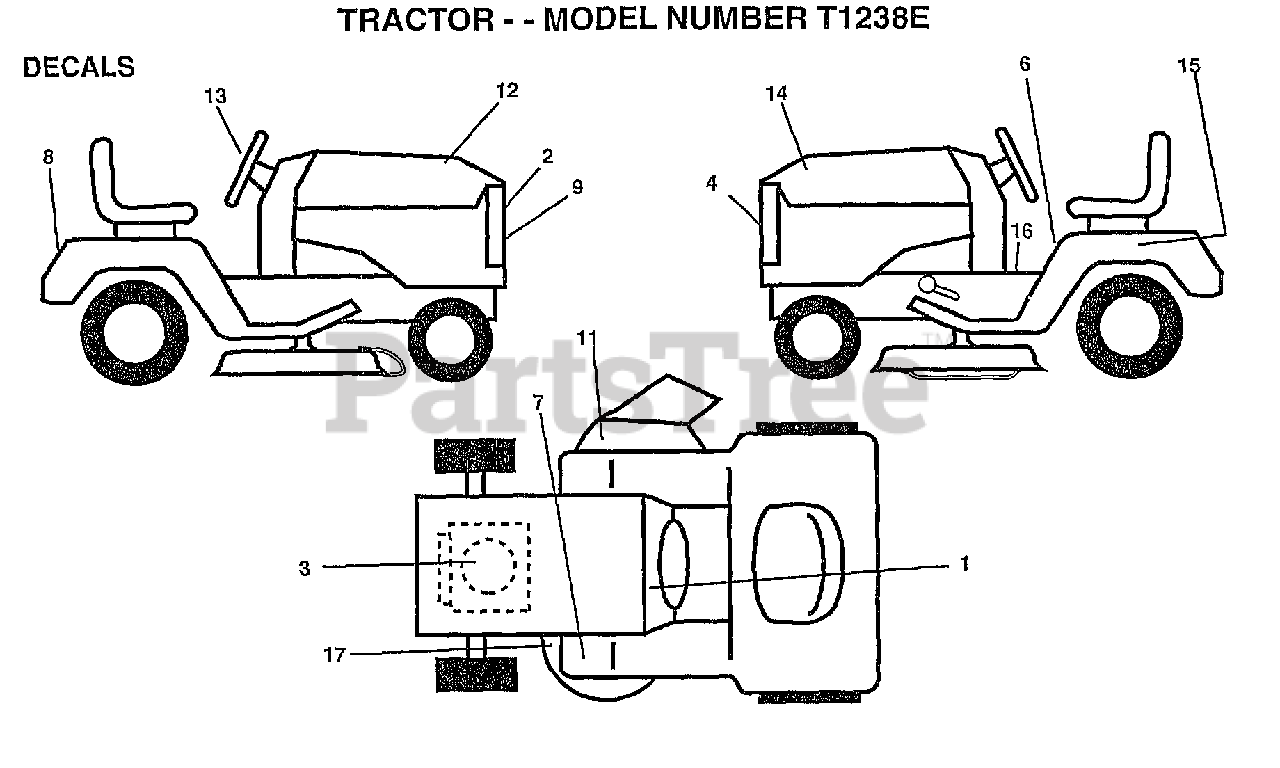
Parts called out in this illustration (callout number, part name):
1	DECAL.DASH.INSTR.
2	"DECAL,GRILL"
3	DECAL, HP ENGINE
4	DECAL GRILLE COOP
6	DECAL CAUTION
7	DECAL T
8	DECAL LOGO FENDER
9	DECAL.STRIPE.GR
11	"DECAL, WARNING"
12	DECAL HOOD RH
13	"DECAL,STR WHL T"
14	DECAL HOOD LH
15	DECAL.BTRY.DANGER
16	DECAL BRAK PARK
17	DECAL
